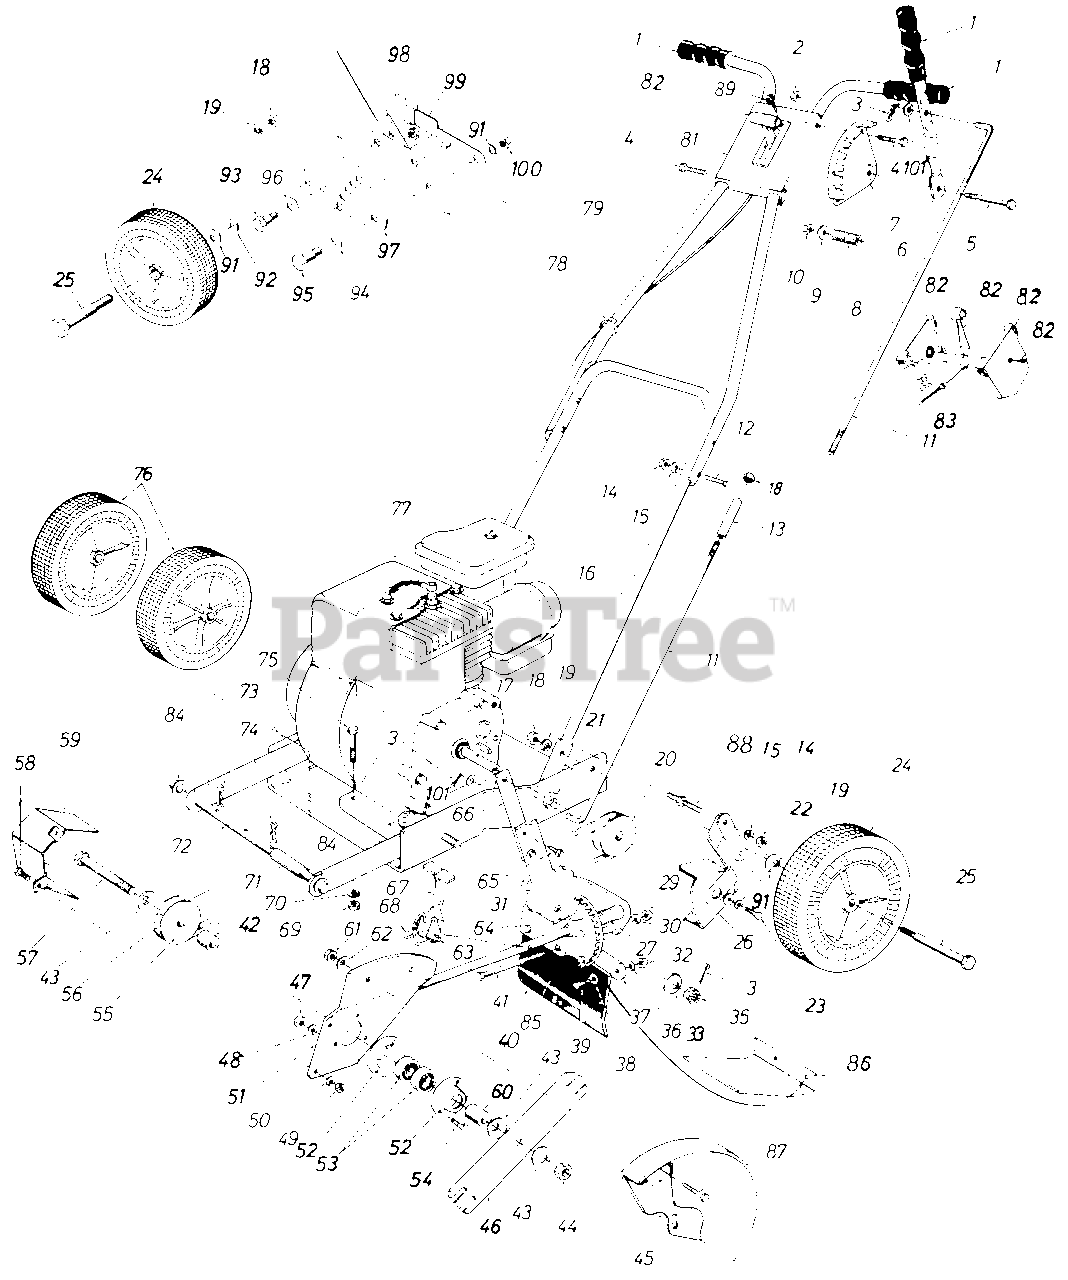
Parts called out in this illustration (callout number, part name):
1	Black Grip
2	Hex L-Nut 1/4-20 Thd.
3	Cotter Pin 1/8" Dia.
4	Hex Bolt 1/4-20 x 1.25" Lg.
5	Hex Bolt 5/16-18 x 2" Lg.
6	Engagement Handle
8	Compression Spring 1.38" Lg.
9	Fl-Wash. .344" I.D.
10	Hex L-Nut 5/16-18 Thd.
11	Clutch Rod Half 18.25" Lg.
12	Carriage Bolt 1/4-20 x 1.25"
13	Rod Adjustment Link
14	Hex Nut 1/4-20 Thd.
15	L-Wash. 114" I.D.*
16	Lower Handle (Painted)
16	Lower Handle (Chrome)
17	Sq. Key 3116" x .75" Lg.
18	Hex Nut 3/8-16 Thd.
19	L-Wash. 318" I.D.
20	Engine Pulley
21	Spacer.75" I.D.
22	Fl-Wash. .385" I.D.
23	Hex Bolt 3/8-24 x 1" Lg.*
24	Rear Wheel Ass'y. 8" x 1.75"
25	Shoulder Bolt .498" Dia.
26	Belt Guard Ass'y.
27	Compression Spring
29	Hex Nut 5/16-18 Thd.
30	L-Wash. 5116" I.D.*
31	Spring Pin Spir. 3116" Dia.
32	Hex Nut 1/4-20 Thd.
33	Bell-Wash. .535" I.D.
35	Hex Slotted Nut 1/2-20 Thd.
36	L-Wash. 114" I.D.
37	Flap Bracket
38	Fl-Wash..25" I.D.
39	Hex Bolt 1/4-20 x .50" Lg.
41	Hex Bolt 5/16-18 x 4.5" Lg.
42	Spacer 1.030n Lg.
43	Bell-Washer. .63" I.D.
44	Hex Jam L-Nut 5/8-18 Thd.
47	Hex Nut 1/4-20 Thd.
48	L-Wash. 114" I.D.
49	Hex Nut 1/4-20 Thd.
50	L-Wash. 114" I.D.*
53	Ball Bearing .62" I.D.
54	Hex Bolt 1/4-20 x .62" Lg.
55	3/8""V"-Pulley
56	V-Belt
57	Hex Bolt 5/8-18 x 4.5" Lg.
58	Hex Bolt 1/4-20 x .625" Lg.
59	Belt Guard
60	Sleeve.90" Lg.
61	Hex Nut 5/16-18 Thd.'
62	Bell-Wash. .345" I.D.
63	Spring Pin Spir. 1/4" Dia.
66	Arm Extension
67	Adjustment Lever Ass'y.
68	Torsion Spring
69	Hex Nut 5/16-18 Thd.
70	L-Wash. 5/16" I.D.
71	Spacer 1.62" Lg.
72	Axle 8.75" Lg. (Front)
73	Base Ass'y.
74	Hairpin Cotter 1/2" Dia.
75	Hex Bolt 5/16-18 x 1.5" Lg.*
76	Front Wheel Ass'y. 7" x 1.50"
77	Engine
78	Cable Tie
79	Upper Handle (Painted)
79	Upper Handle (Chrome)
83	Throttle Control Wire 30" Lg.
84	Push Cap 1/2" Dia.
85	Spacer 3.765" Lg.
88	Stud 1/4-20 x 2.12" Lg.
89	Self-Tap Scr. #10 x .50" Lg.
91	Bell-Wash. .40" I.D.
92	Fl-Wash. .39" I.D.
93	Shld. Bolt.5" Dia.
94	Bell-Wash. .515" I.D.
95	Shld. Bolt .50" Dia.
96	Fl-Wash. .51" I.D. x .94"
99	Spring Adj. Lever
100	Hex Jam Nut 3/8-16 Thd.
101	Fl-Wash. 3/8" I.D.
